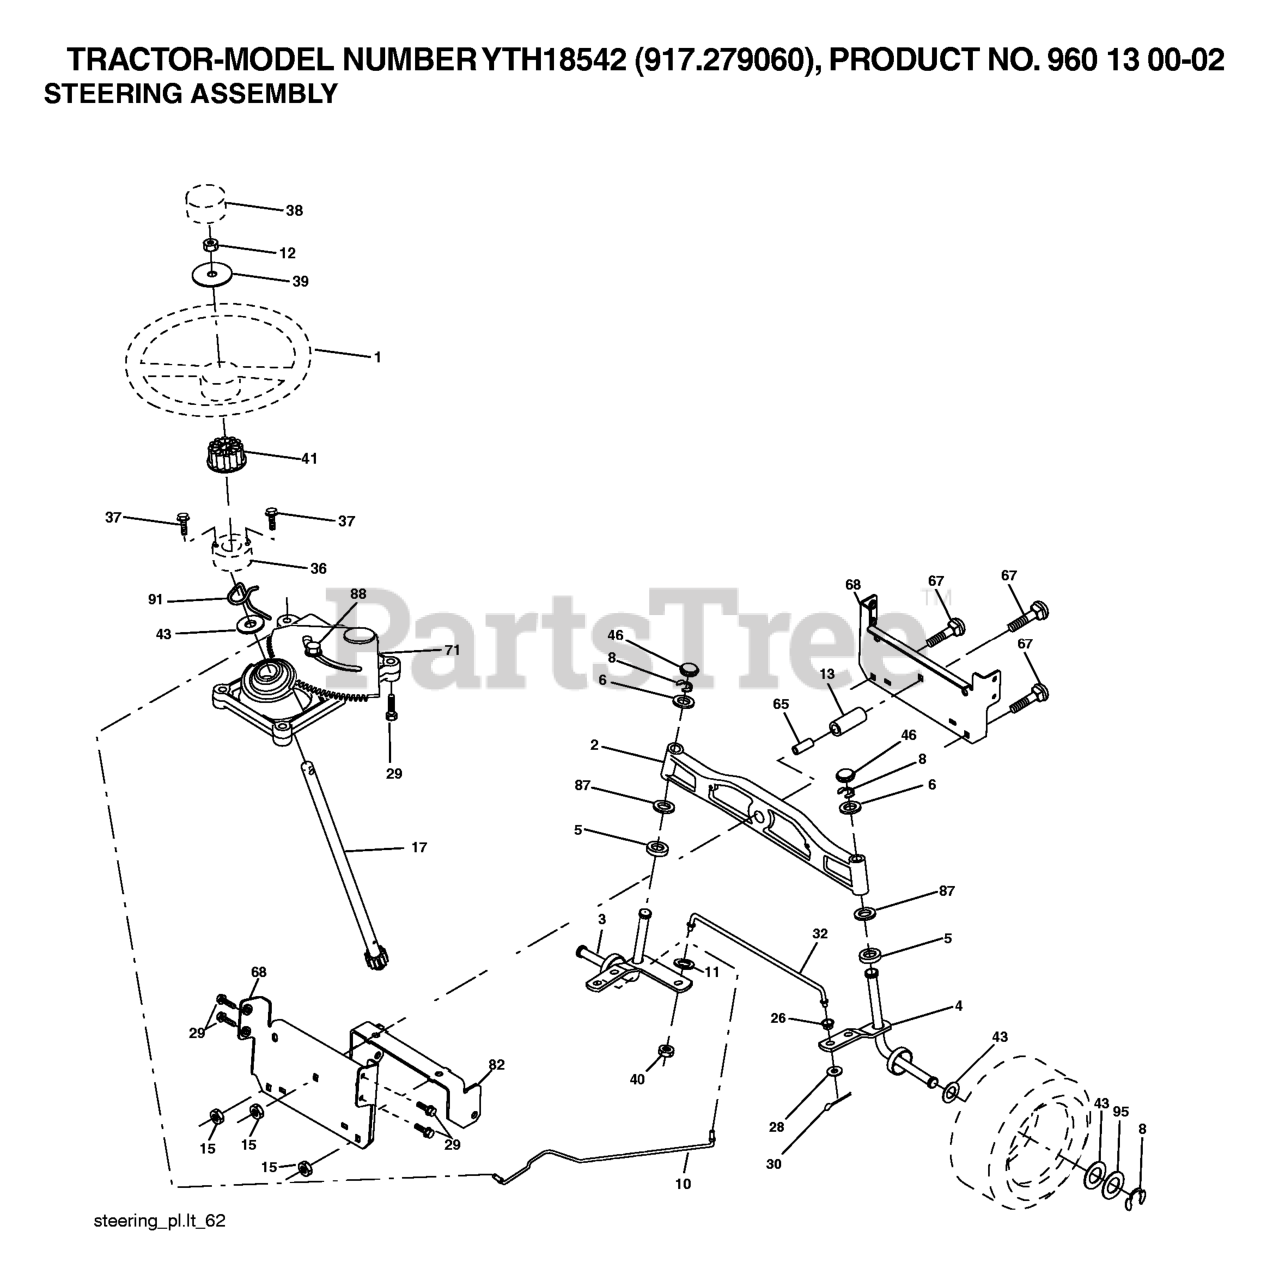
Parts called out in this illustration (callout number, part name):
1	WHEEL.STEERING.LEGEND2.GRY
2	AXLE ASSY FRONT
3	SPINDLE.ASM.LH.15"TIRES
4	SPINDLE.ASM.RH.15"TIRES
5	THRUST WASHER
10	DRAGLINK.15".TIRES.2001
11	WASHER, LOCK 3/8
12	NUT.HEX.1/2-20
13	TUBE, PIVOT AXLE
15	NUT
17	SHAFT ASM STRG
26	BUSHING.DRAGLINK (2 2)
28	WASHER
29	SCREW, 3/8-16X3/4
30	COTTER PIN
32	ROD.TIE.WIRE.FORM
36	BUSHING, STRG. BLK
37	SCREW.TT.#10-32X.5.3/8.FLANGE
38	INSERT.CAP.STRG.WH.GRAY
39	WASHER 9/16"ID, 2 3/8"OD
40	NUT CROWNLOCK 3/8-24
41	ADAPTER, WHEEL STNG..
46	CAP.SPINDLE.BLACK
65	SPACER BRACE AXLE
67	BOLT CARRIAGE
68	BRACE.AXLE.15"TIRES
71	STEERING ASM
82	BRACKET
87	WASHER, FLAT .781 X 1 1/2"
88	BOLT, SHOULDER 7/16-20
91	CLIP.STEERING
95	WASHER.HARDENED
